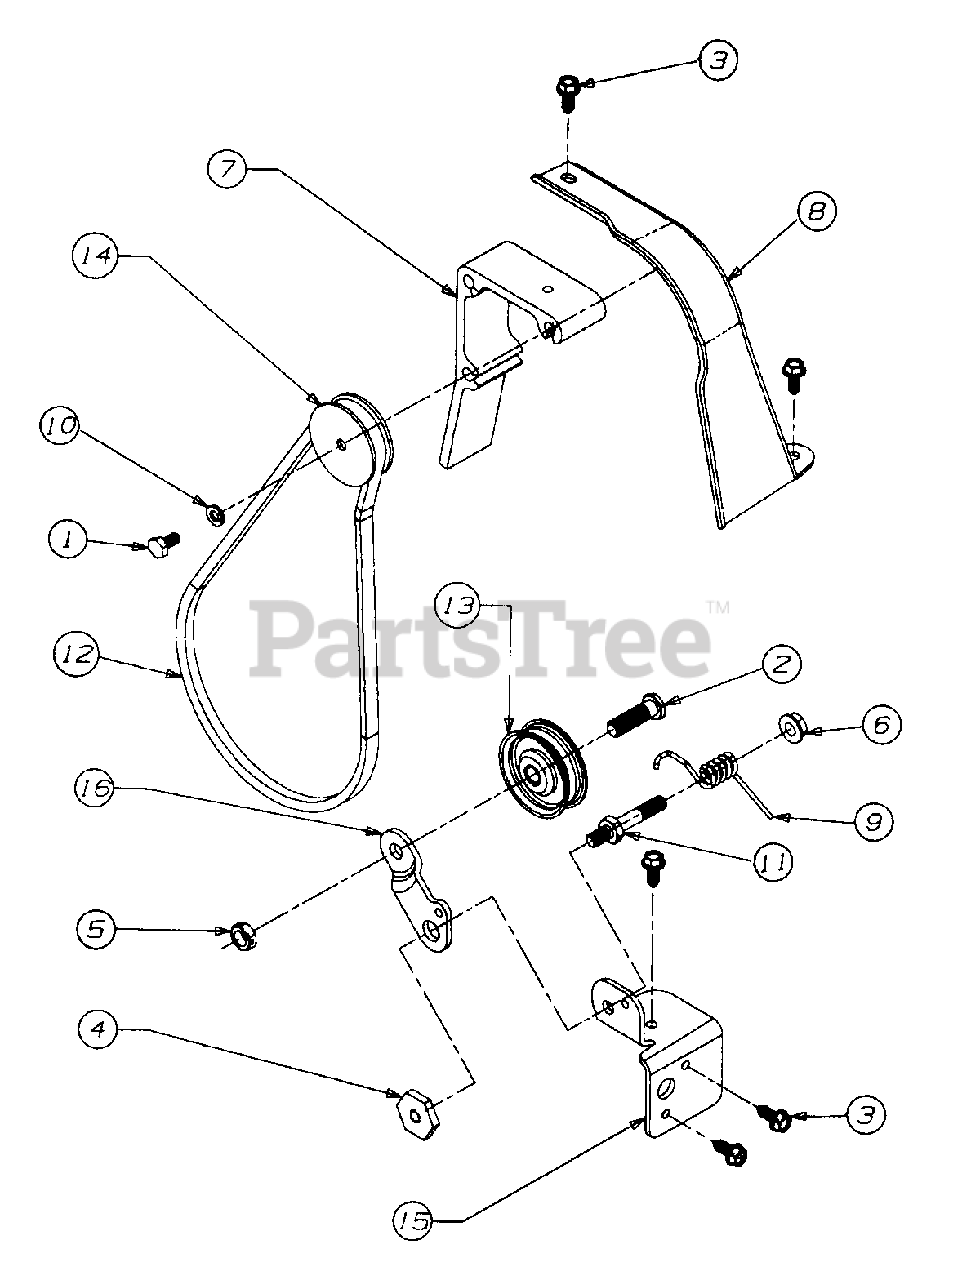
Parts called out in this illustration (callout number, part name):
4	NUT - HEX SHOULDER
5	NUT - HEX LOCK
6	NUT - HEX LOCK FLANGE
7	ADAPTER - MOUNTING
10	WASHER - LOCK
11	BOLT - IDLER
12	V - BELT
13	IDLER - FLAT
